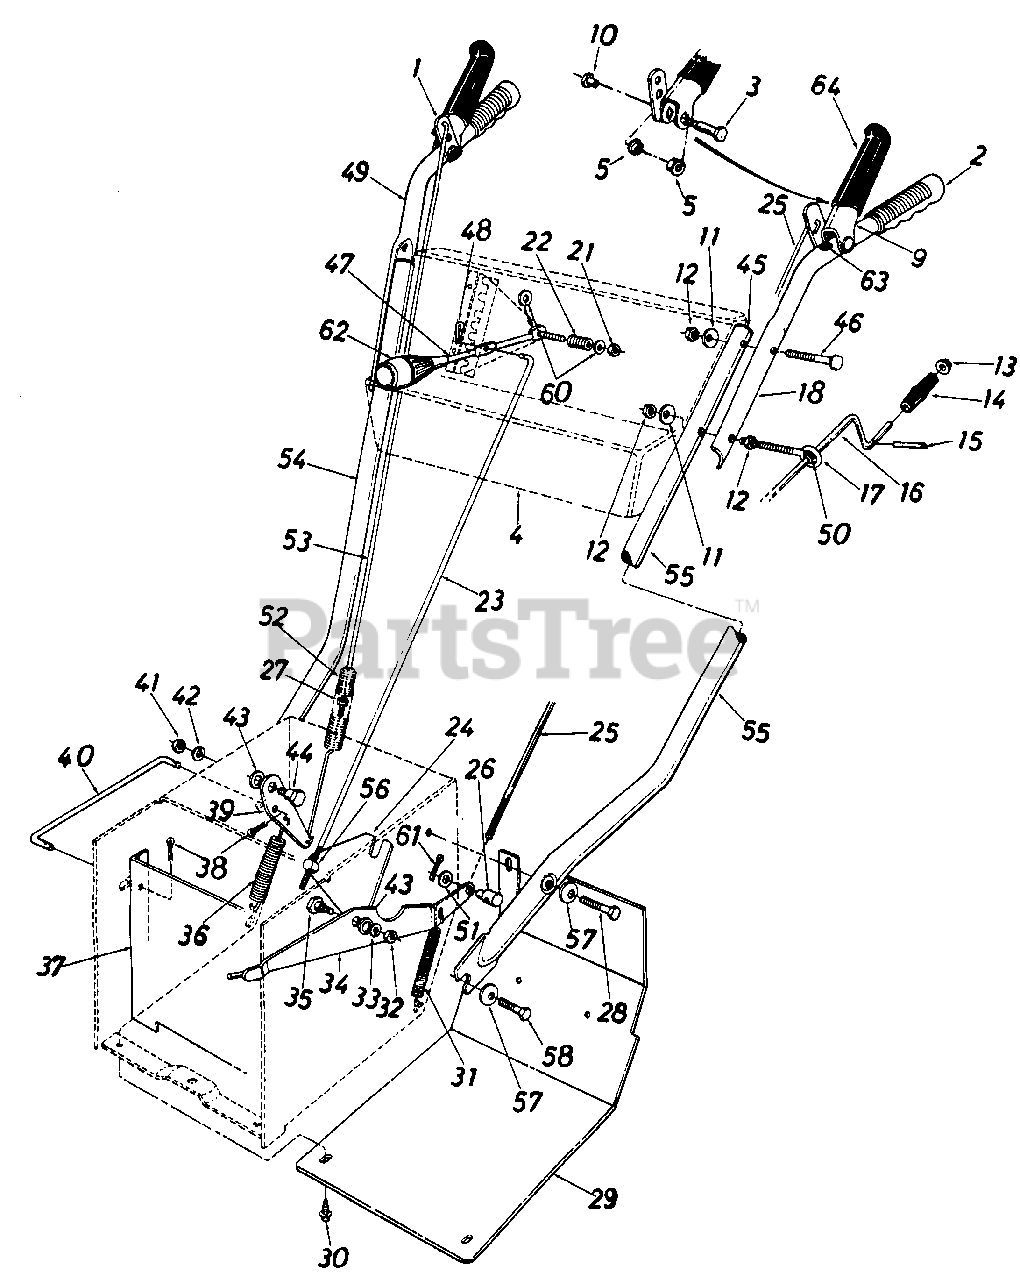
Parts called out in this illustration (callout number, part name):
1	GRIP ASSY-LH CLUTCH 2-STG S/T MTD
3	SCREW-SHLD .374 DIA X1.530
4	PANEL ASSY-HANDLE
5	BEARING-FLANGE
9	GRIP ASSY-LH CLUTCH 2-STG S/T MTD
10	NUT-SHLD
11	WASHER-BELL .337 X .867 X .057
12	NUT-HEX 5/16-18
14	KNOB-CHUTE CRANK
15	PIN-ROLL 1/18 DIA
16	CRANK ASSY-CHUTE
18	HANDLE-FOLDING-LH PAINTED
21	NUT-HEX INS L-5/16-18
22	SPRING-COMPRESSION
24	BRACKET-LINKAGE
25	ROD-CLUTCH
26	FERRULE-ADJ
27	NUT-INS LOCK 1/4-20
28	SCREW-HEX 3/8-16 X 2.00
29	Fram Cover
30	SCREW-HEX WASH SF TAPP
31	SPRING-EXTENSION
32	NUT-HEX JAM 3/8-18
33	WASHER-LOCK-3/8
34	BRACKET-AUG CLUTCH
35	SCREW-SHLD .625 DIA X .163
36	SPRING-IDLER EXTN
37	BRACKET ASSY-PULLEY SUP
38	BRACKET ASSY-PULLEY SUP
39	PIN-COTTER-3/32 DIA X .75
40	ROD-VAR SP CLUTCH
41	NUT-HEX JAM 3/8-18
42	WASHER-LOCK-3/8
43	WASHER-BELL .3/8ID X 1.12OD X .030
44	SCREW-SHLD .625 DIA X .163
46	BOLT-CARRIAGE 5/16-18 X 2.00
47	HANDLE-SHIFT
48	PIN-INTERN COT-5/16 DIA
51	WASHER-FL-.344 X .62
53	ROD-LOCKOUT
54	HANDLE-LOWER-RH PAINTED
55	HANDLE-LOWER-LH PAINTED
56	FERRULE
57	WASHER-BELL .400 ID X .88 X .060
58	SCREW-HEX WASH SF TAPP 3/8 X 3/4
60	WASHER-FL-.344 X .62
61	PIN-COTTER-3/32 DIA X .75
63	CAP-PUSH
64	VINYL-PLASTIC
